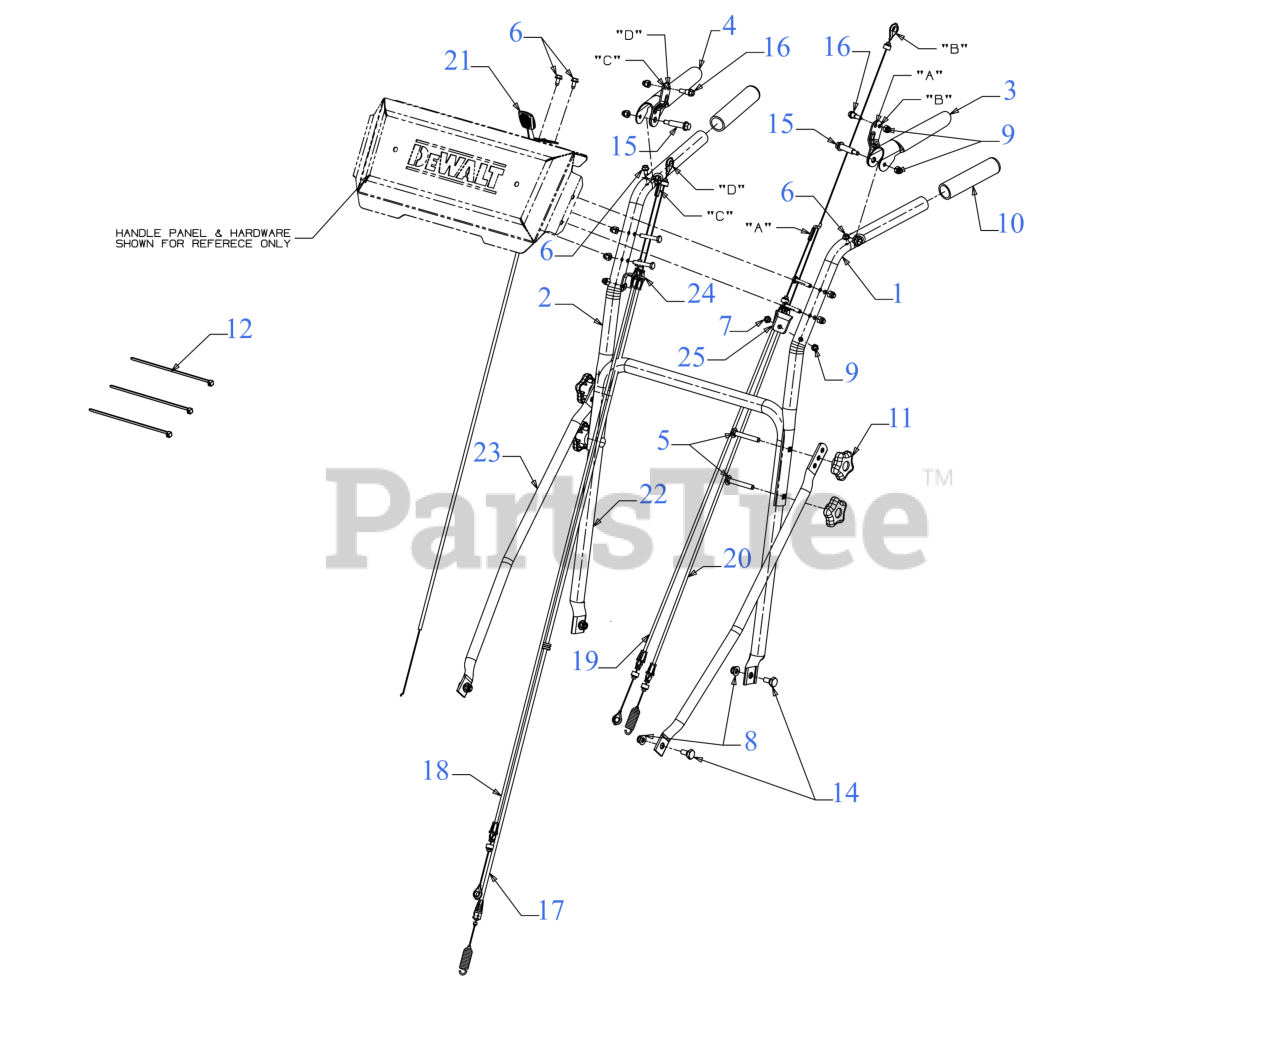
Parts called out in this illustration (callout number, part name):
1	HANDLE ASSEMBLY (UPPER) (LH)
2	HANDLE ASSEMBLY (UPPER) (RH)
3	LEVER ASSEMBLY (LH)
4	LEVER ASSEMBLY (RH)
5	BOLT 5/16-18 x 2.50 GR1
6	SCREW 1/4-20 X.500
7	SCREW 1/4-20 x 1.50 GR.5
8	FLANGE LOCK NUT 5/16-18
9	HEX ACORN NUT
11	STAR KNOB 5/16-18
12	7" CABLE TIE
14	SHOULDER SCREW .437 DIA x .180
15	SHOULDER BOLT .375X1.285:1/4-20
16	SHOULDER SCREW .342X.335X1/4-20
17	BLADE CONTROL CABLE
18	TRANSMISSION BRAKE CABLE (RH)
19	TRANSMISSION BRAKE CABLE (LH)
20	WHEEL CLUTCH CABLE
21	THROTTLE CABLE
22	HANDLE (LOWER)
23	HANDLE BRACE TUBE
24	CABLE BRACKET MOUNTING (RH)
25	CABLE BRACKET MOUNTING (LH)
